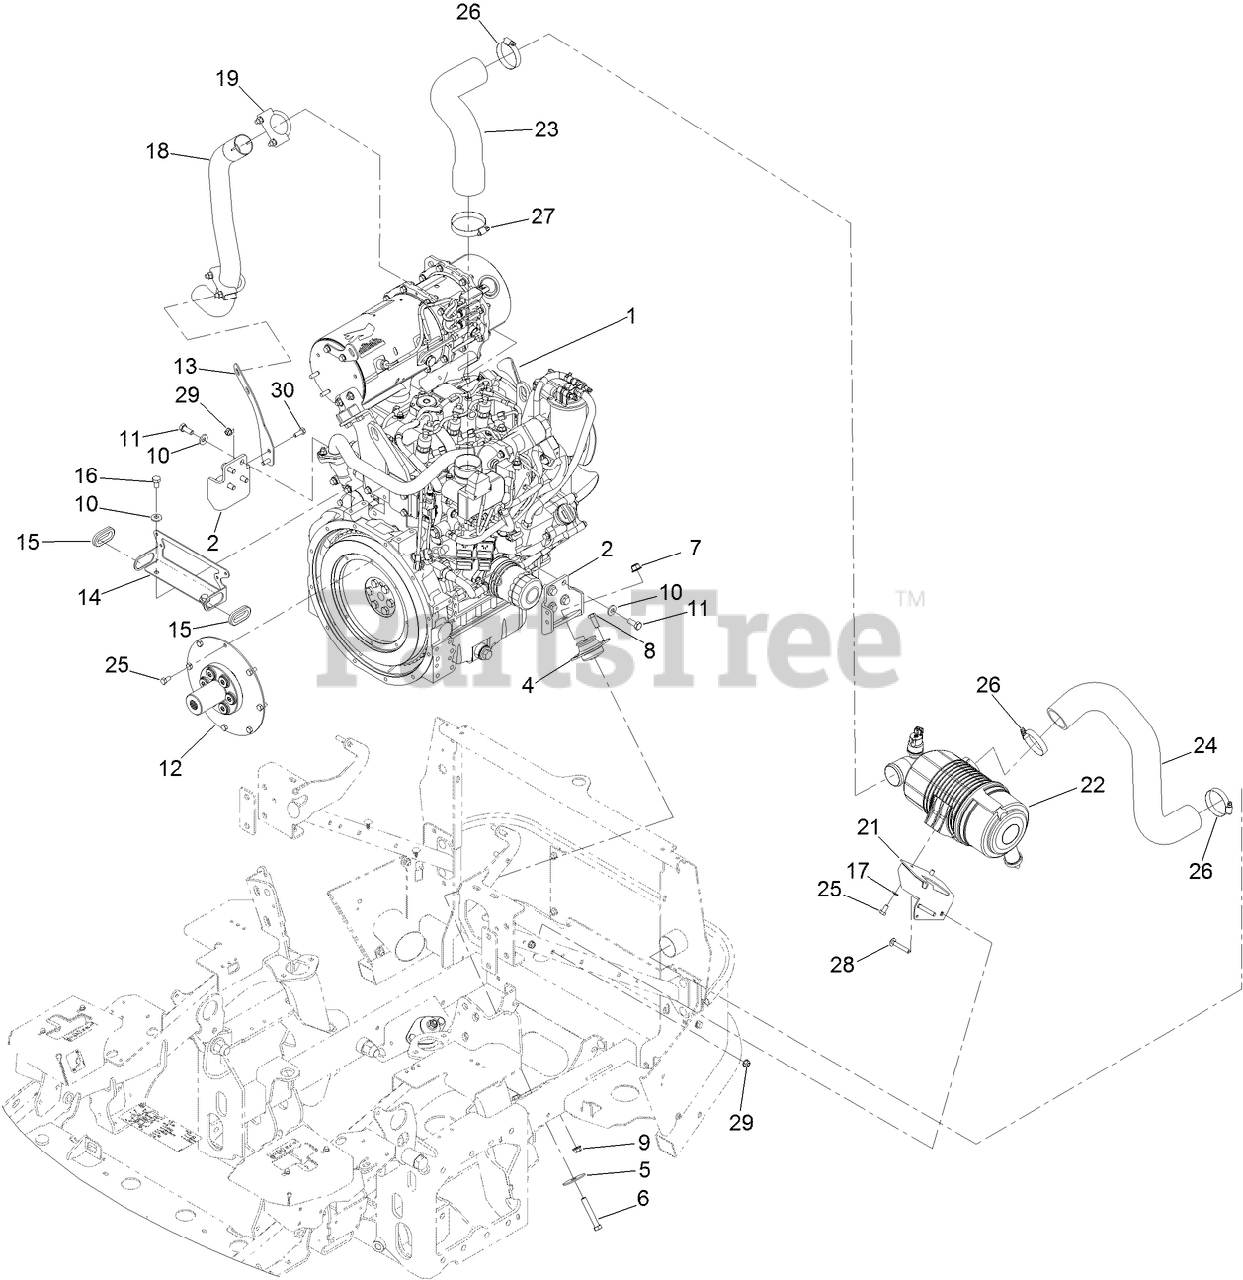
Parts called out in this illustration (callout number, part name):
1	SEE PACKAGED ENGINE 138-6927
2	MOUNT-MOTOR, UPPER
5	WASHER-SNUBBING
6	SCREW-HH
7	NUT-HF, NI
8	SCREW-HH
9	NUT-HF, NI
10	WASHER-BELLEVILLE
11	SCREW-HH
12	COUPLING-FLYWHEEL
13	BRACKET-MOUNT
14	BRACKET-GUIDE
15	GROMMET-RUBBER
16	SCREW-HH
17	WASHER-BELLEVILLE
18	TUBE-EXHAUST
19	CLAMP
21	BRACKET-CLEANER, AIR
22	AIR CLEANER ASM
23	HOSE-AIR
24	HOSE-AIR
25	BOLT
26	CLAMP-HOSE
27	CLAMP-HOSE
28	BOLT-CARR
29	NUT-HF, NI
30	SCREW-HH
